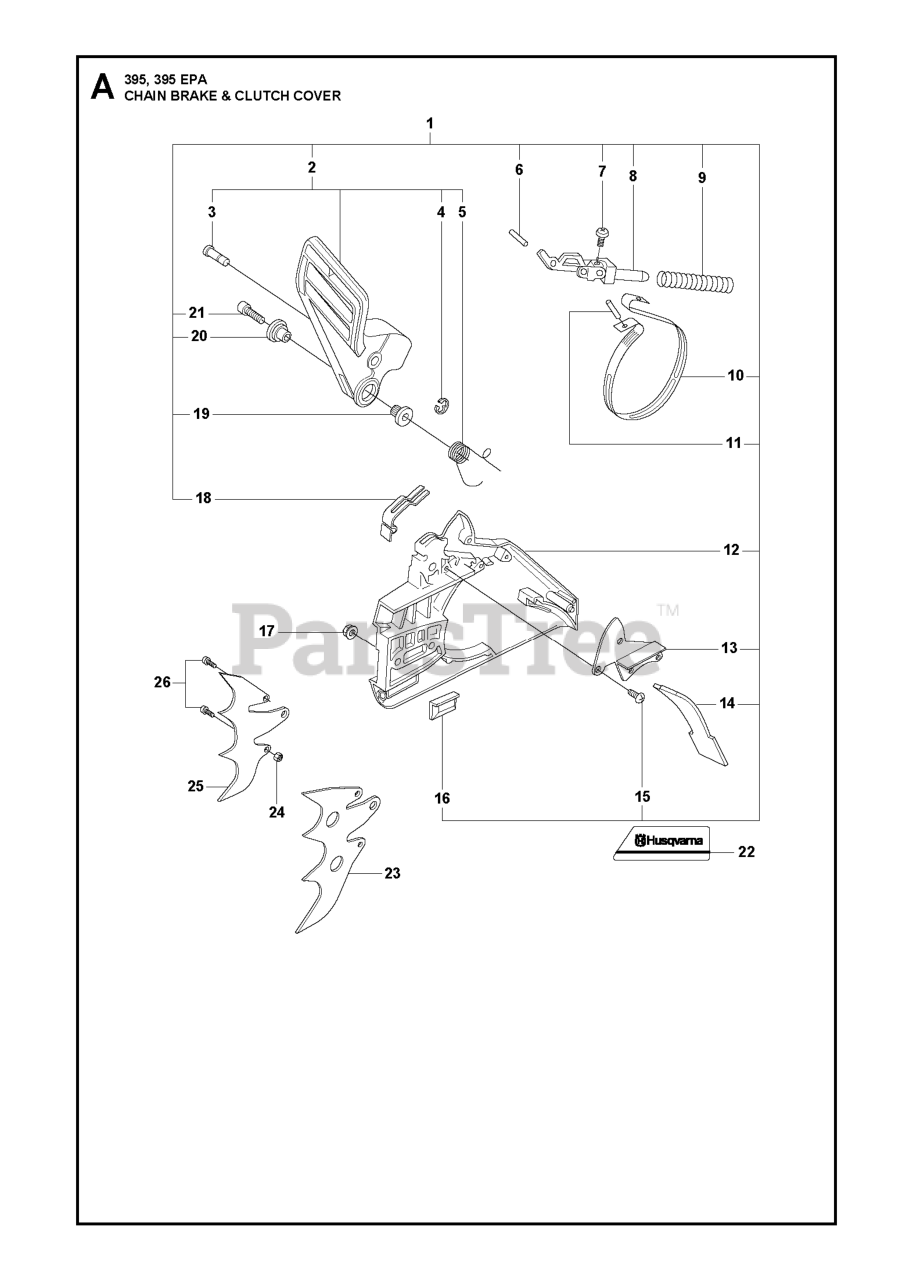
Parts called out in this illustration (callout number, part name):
1	CHAINBRAKE
8	KNEE-JOINT
9	BRAKE SPRING
10	BRAKE BAND
11	SPIRAL PIN 4X12
12	CLUTCH COVER
16	CHAIN GUIDE
17	NUT M8 FLANGE
19	PIVOT SLEEVE L
20	PIVOT SLEEVE R
23	FELLING DOG
25	FELLING DOG
26	SCREW
